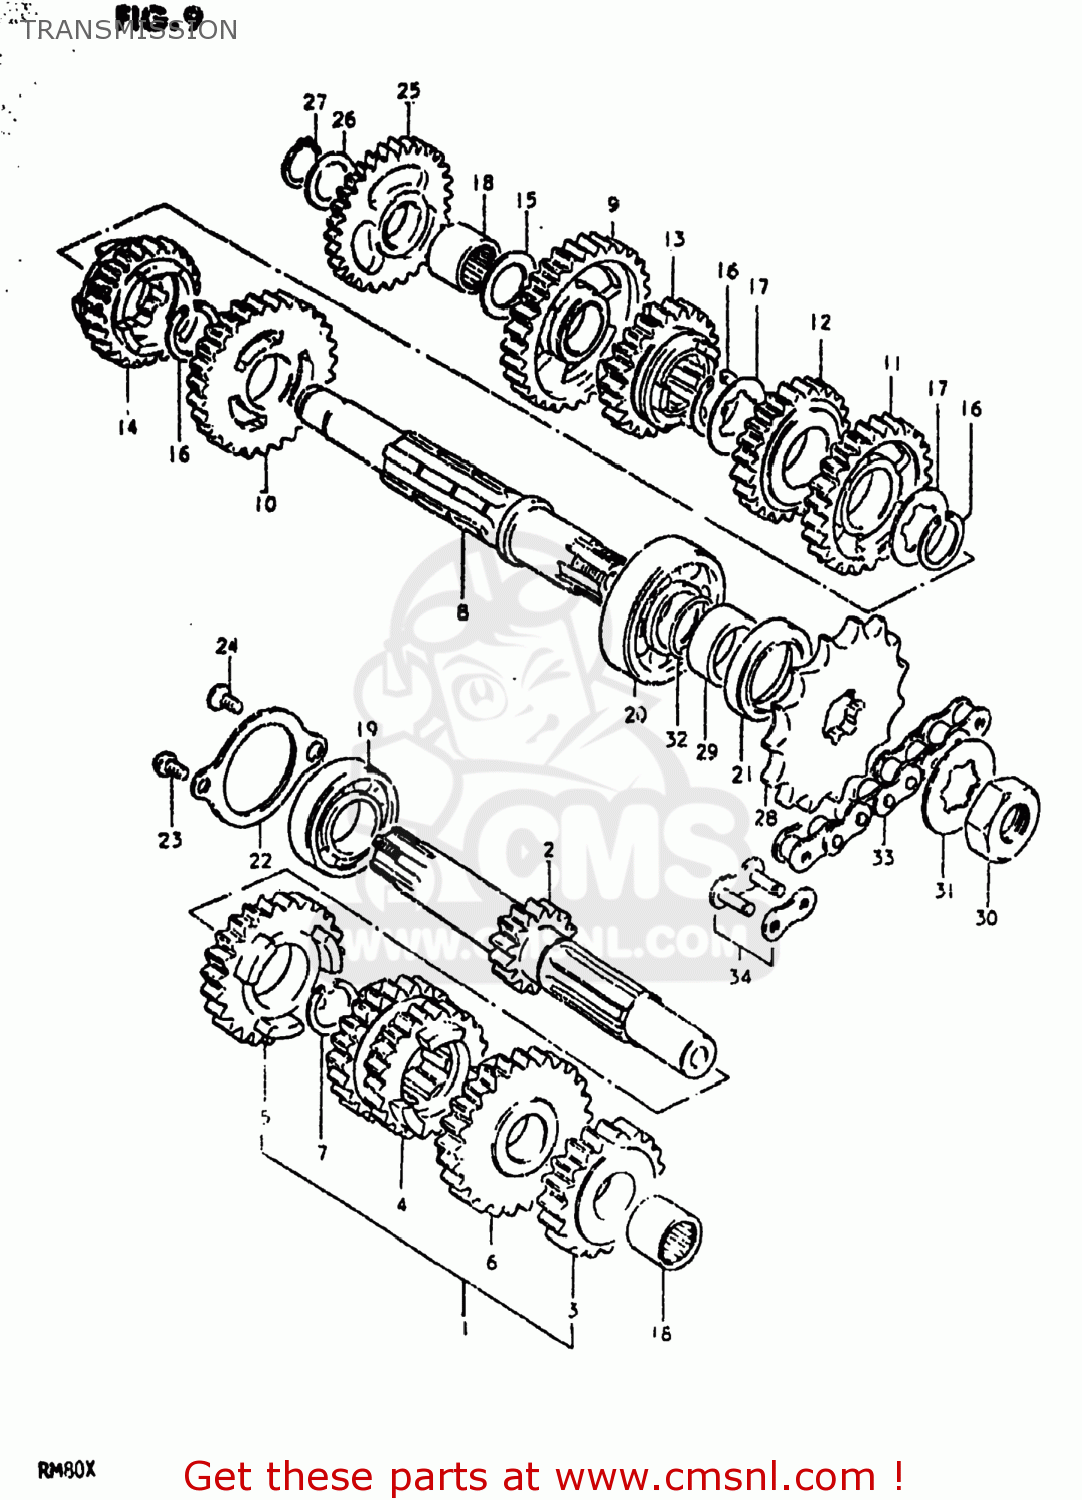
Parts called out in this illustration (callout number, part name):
1	SHAFT,COUNTER
2	SHAFT,COUNTER
3	GEAR,SECOND DRIVE
4	GEAR,THIRD/FOURTH DRIVE
5	GEAR,FIFTH DRIVE
6	GEAR,SIXTH DRIVE
7	CIRCLIP
8	SHAFT,DRIVE
9	GEAR,FIRST DRIVEN
10	GEAR,SECOND DRIVEN
11	GEAR,THIRD DRIVEN
12	GEAR,FOURTH DRIVEN
13	GEAR,4TH DRIVEN(NT:36)
14	GEAR,SIXTH DRIVEN
15	WASHER(13X24X1)
16	CIRCLIP
17	WASHER,LOCK
18	ROLLER BEARING (13X19X1
19	BEARING
20	BEARING
21	SEAL,OIL(21X35X5)
22	RETAINER,CNTR SHAFT BEARING
23	SCREW
24	SCREW
25	GEAR,KICK STARTER IDLE
26	WASHER
27	CIRCLIP
28	SPROCKET,ENGINE
29	SPACER (17X21X11)
30	NUT
31	WASHER,LOCK
32	O RING(D:1,ID:16.8)
33	CHAIN ASSEMBLY,DRIVE
34	JOINT ASSEMBLY,CHAIN
